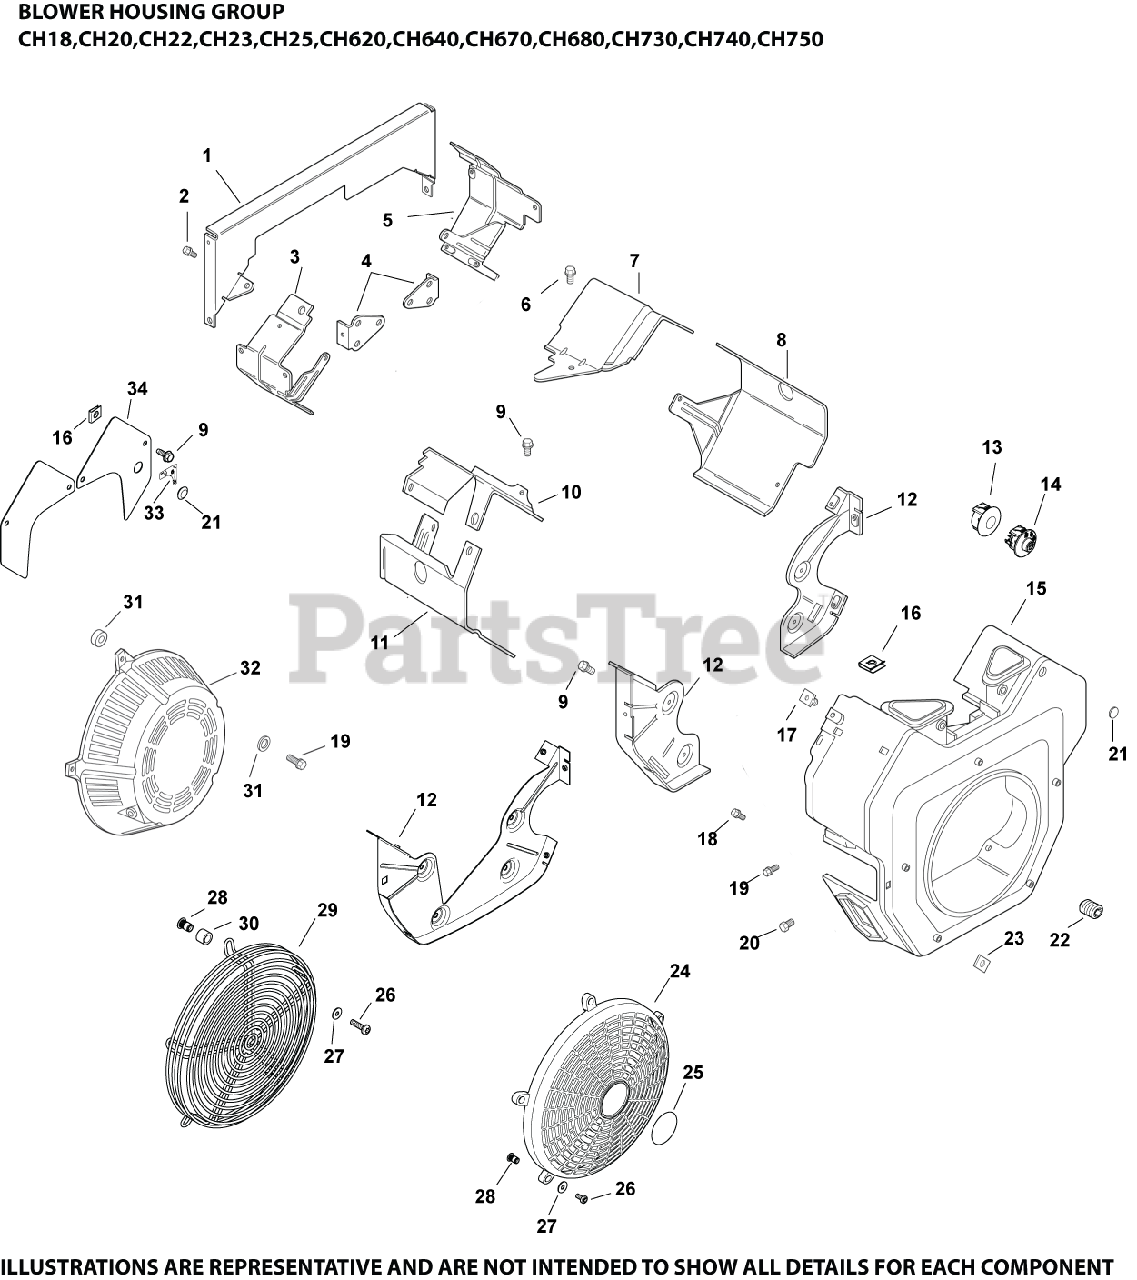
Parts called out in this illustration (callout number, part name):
6	SCREW, THREAD FORMING
7	BAFFLE, VALLEY #1 CYLINDER
8	KIT, CYL BAFFEL #1 SIDE
9	SCREW, THREAD FORMING
10	BAFFLE, VALLEY #2 CYLINDER
11	KIT, CYL BAFFEL #2 SIDE
12	KIT, BACKING PLATE
15	HOUSING, BLOWER
19	SCREW, THREAD FORMING
